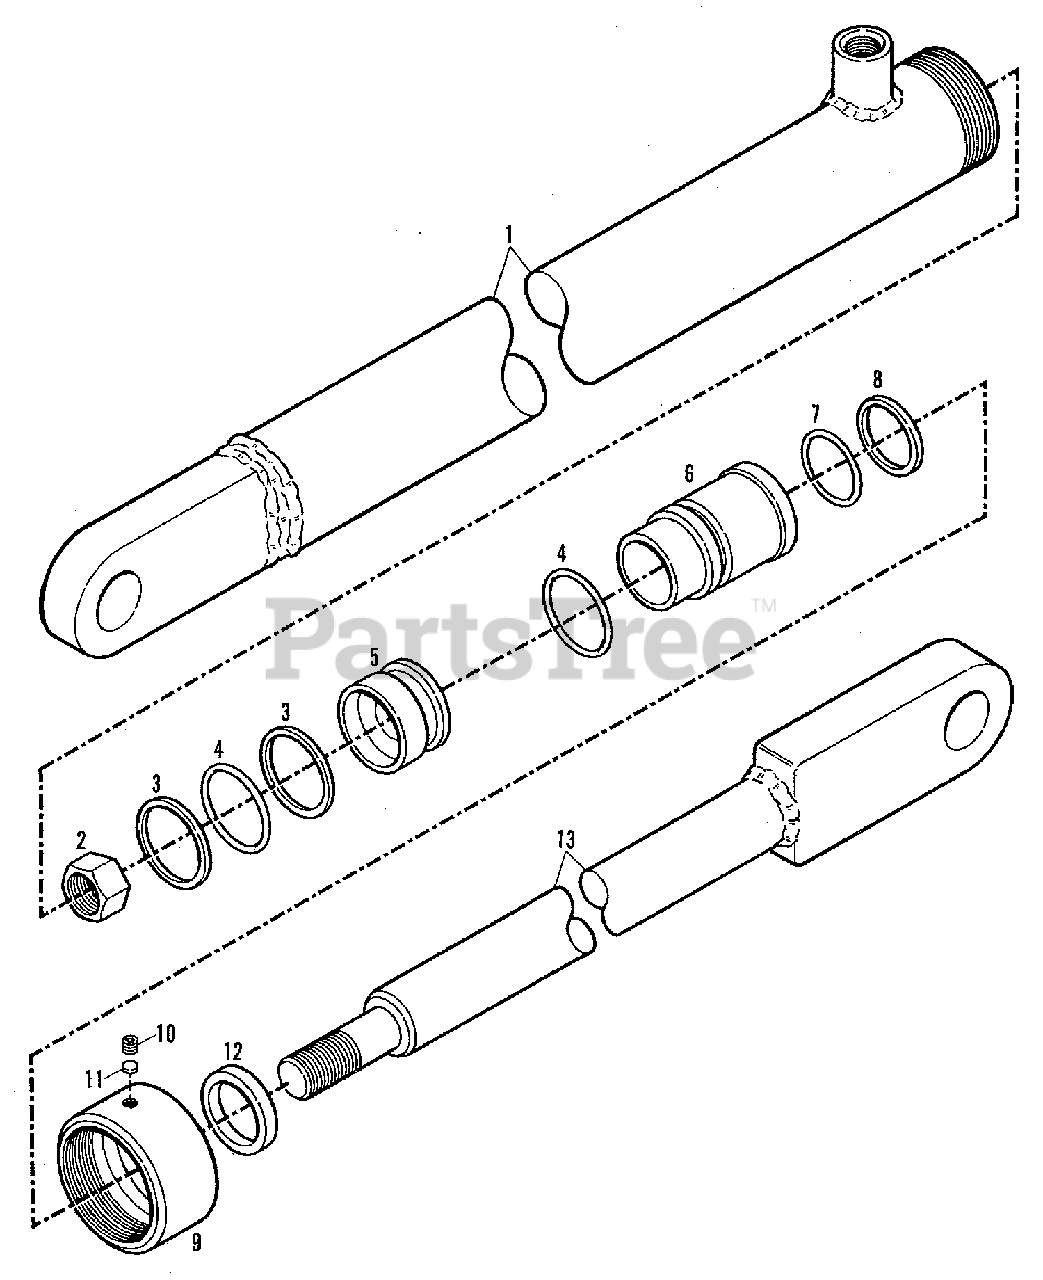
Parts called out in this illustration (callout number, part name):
1	TUBE ASSEMBLY
2	NUT, Piston Rod Assembly
3	WASHER, Backup, Piston
4	O-RING
7	O-RING
8	WASHER, Backup
10	SETSCREW, Cap
11	PLUG, Nylon
12	WIPER, Rod
13	ROD ASSEMBLY, Piston
